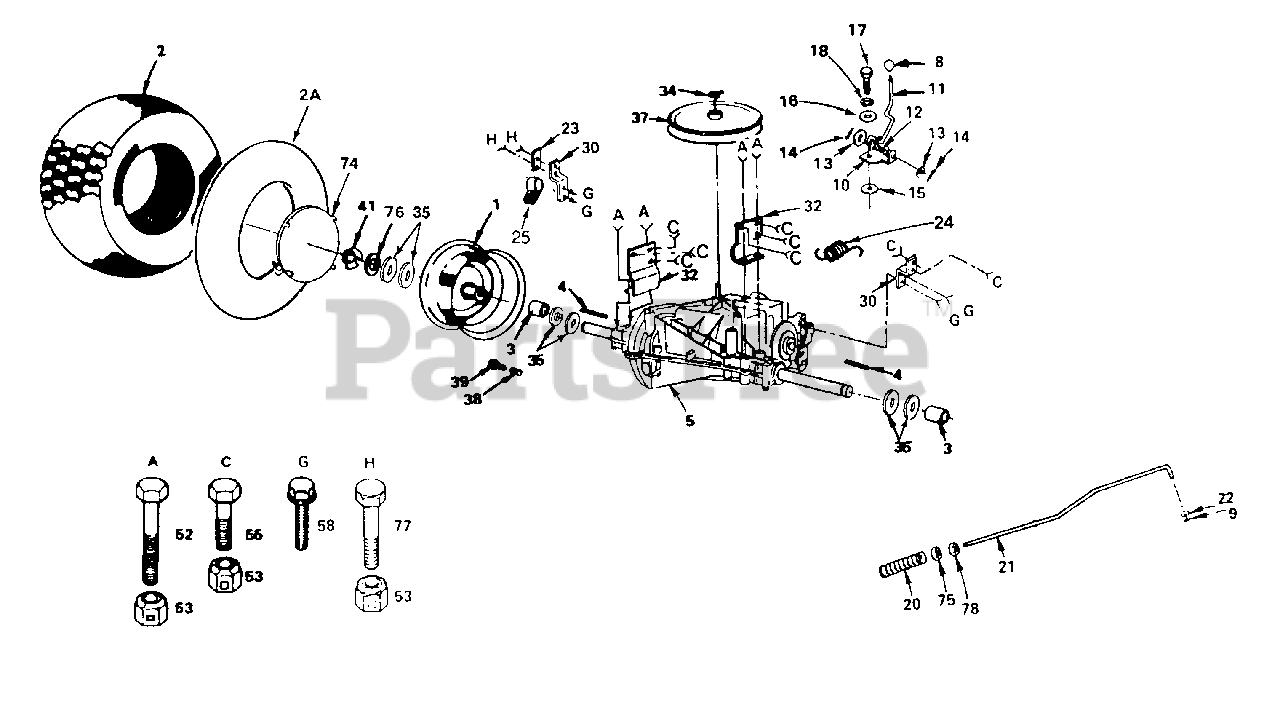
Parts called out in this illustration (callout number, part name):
1	Rim Assembly 8" Rear
2	Tire, 18 x 9.50 - 8 (Tubeless)
2A	Tube, Tire
3	Spacer, Split
4	Key, Square 3/16 x 2.5
5	Transaxle, 6 Speed, Model No.4360-19
8	Knob, Control
9	Cotter Pin, 1/8 x 3/4
10	Plate, Rod, Shift
11	Rod, Shifter
12	Spring, Torsion
13	Washer, 15/32 x 3/4 x 16 Ga.
14	Pin, Cotter 1/8 x 1
15	Washer, Shift Plate
16	Washer, 9/32 x 3/4 x 10 Ga.
17	Bolt, Hex 1/4- 28 x 3/4, Gr.8
18	Washer, Lock 1/4
20	Spring, Rod, Brake
21	Rod, Brake
22	Washer, 13/32 x 13/16 x 16 Ga
23	Plate, Strap, Torque
24	Spring, Brake Return
25	Clip
30	Strap, Torque
32	Bracket, Transaxle
34	Ring, Klip
35	Washer, 25/32 x 1-1/4 x 16 Ga.
37	Pulley, Transaxle
38	Cap, Valve
39	Stem, Valve
52	Bolt, Hex 3/8-16 x 2-3/4
53	Nut, Lock 3/8-16
55	Bolt, Hex 3/8 - 16 x 3/4
58	Screw, Hex Washer Hd. Thd Forming, Type TT 5/16 18 UNC x 3/4
74	Cap, Hub, Rear
75	Nut, Lock, Hex, Washer Insert, 3/8-16
76	Washer, 25/32 x 1-5/8 x 16 Ga.
77	Bolt, Hex 3/8-16 x 1
78	Nut, Hex Jam, 3/8 - 16
